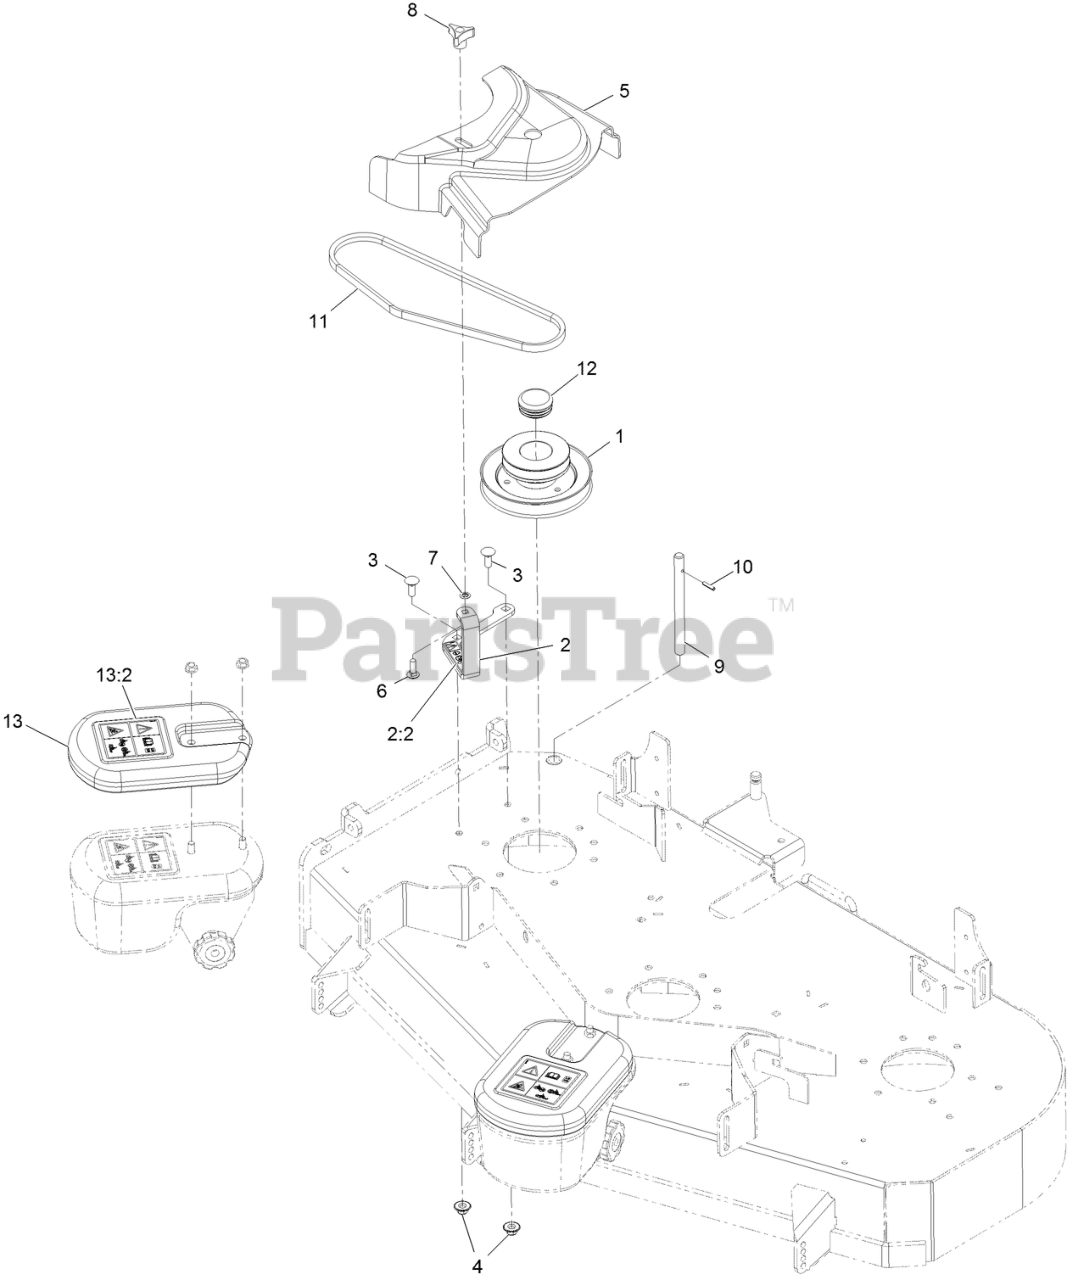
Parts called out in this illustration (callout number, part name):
1	JACKSHAFT-UV DRIVE, 484 SPLINED
2	ASM-CVR BRKT W/DECAL
2:2	DECAL-DANGER
3	BOLT-CARR
4	Nut-Nyloc 3/8-16 Flg
5	COVER-BELT, UV 48 ENTRY
6	BOLT-CARR
7	RING-RETAINING, BOLT
8	KNOB-3 PRONG
9	SHAFT-CATCHER, GRASS
10	PIN-ROLL
12	PLUG-ROUND PLASTIC
13:2	DECAL-WARNING, TRACTION
